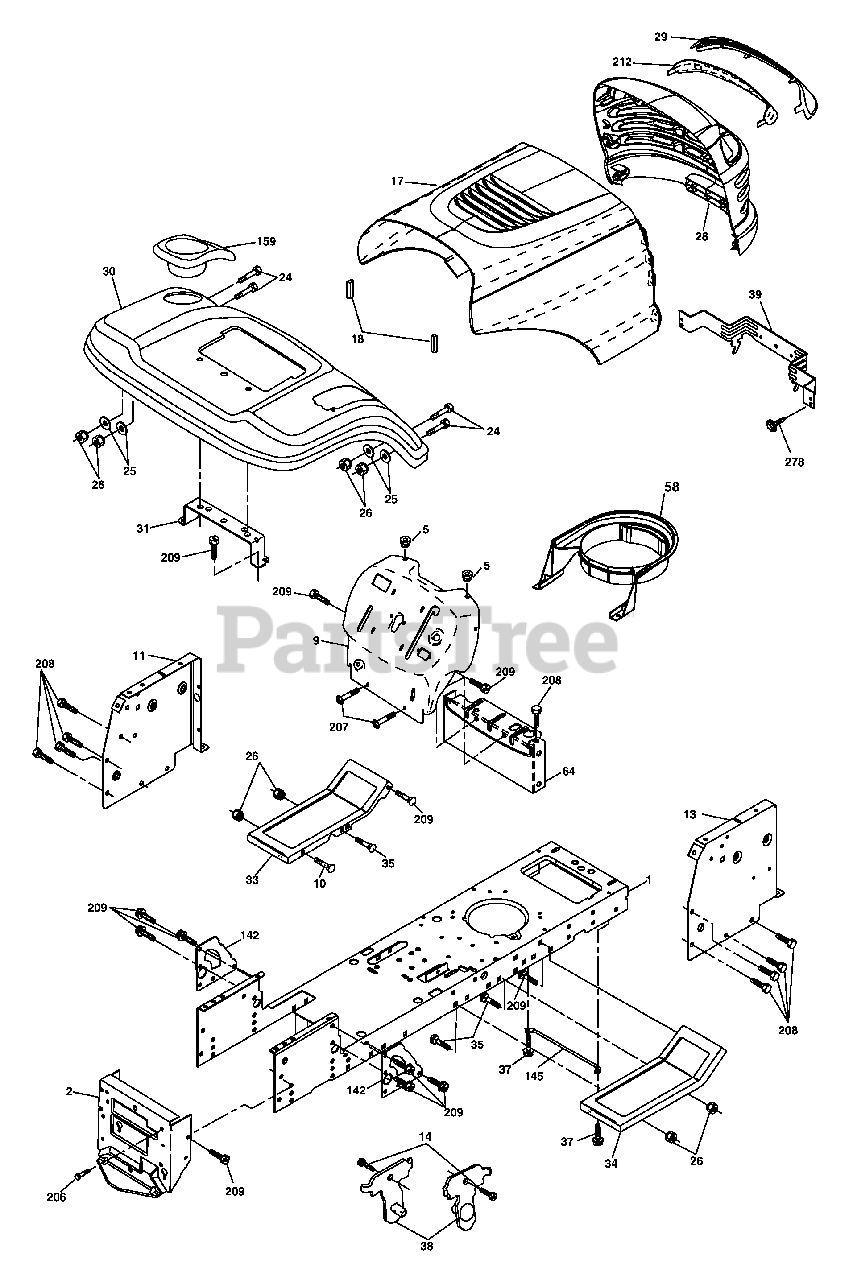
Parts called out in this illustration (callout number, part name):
1	Chassis
2	Drawbar
5	Bumper Hood/Dash
10	Bolt Carriage 3/8-16 x 1
11	Panel Dash Lh
14	Screw Thdrol 3/8-16 x 1/2
17	Hood
18	Bumper Hood
24	Bolt Fin Hex 3/8-16 unc x 1 Gr. 5
25	Washer 13/32 x 3/4 x 12 Ga.
26	Nut Lock Hex W/Ins 3/8-16 unc
28	Grille/Lens Asm
29	Lens Grille
30	Fender
31	Bracket Fender
33	Footrest LH
34	Footrest RH
35	Bolt Rdhd Sqnk 3/8-16 x 3/4
37	Screw Thdrol 6/16-18 x 1/2 TYT
38	Bracket Asm Pivot Mower Rear
39	Bracket Pivot
58	Duct Air
64	Dash Lower STLT
142	Plate Reinforcement STLT
145	Rod Pivot Chassis/Hood
159	Cupholder
206	Bolt Shoulder 5/16-18
207	Screw Thdrol 5/16-18 x 1/2
208	Screw Thdrol 3/8-16 x 1/2
209	Screw Hexwsh Thdr 3/8-16 x 3/4
212	Insert Lens Reflective
278	Screw 10 x 3/4 Single Lead Hex
